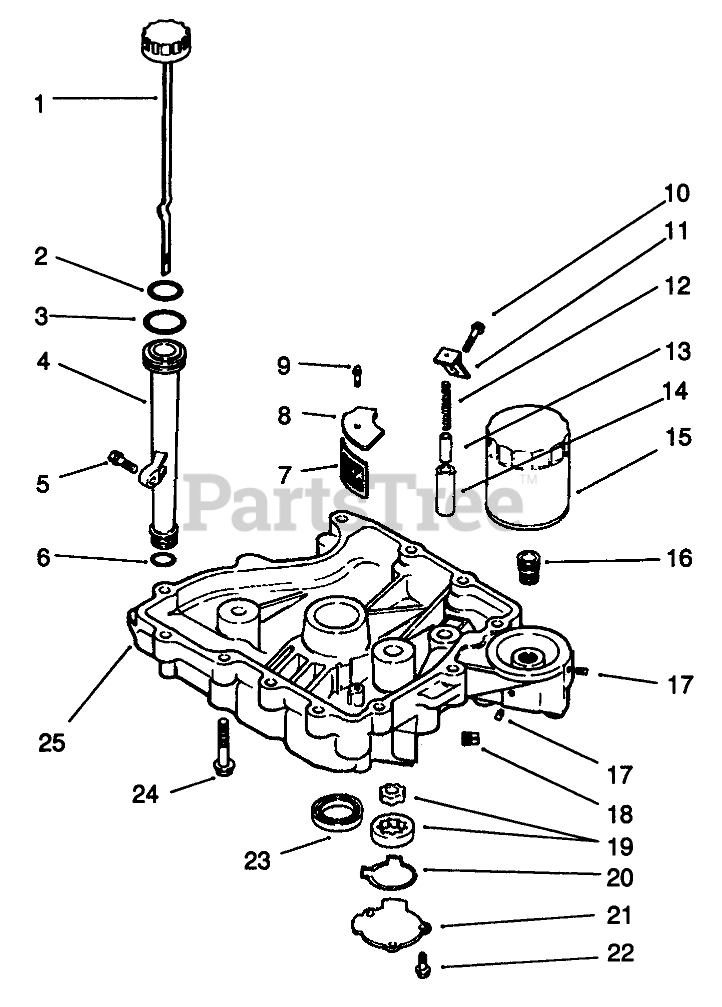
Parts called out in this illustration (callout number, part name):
1	Dipstick INC 2-3
2	"O"Ring
3	"O"Ring-Upper Tube
4	Tube-Oil Fill
5	Screw
6	"O"Ring
7	Screen-Oil Pickup
8	Cover-Oil Screen
9	Screw
10	Screw
11	Bracket-Relief Valve
12	Spring-Relief Valve
13	Piston-Relief Valve
14	Body-Relief Valve
15	Filler-Oil
16	Adapter-Oil Filler
17	Plug-SH 1/8
18	Plug
19	Pump-Oil
20	"O" Ring-Oil Pump
21	Cover-Oil Pump
22	Screw
23	Seal-Oil
25	Pan-Oil
